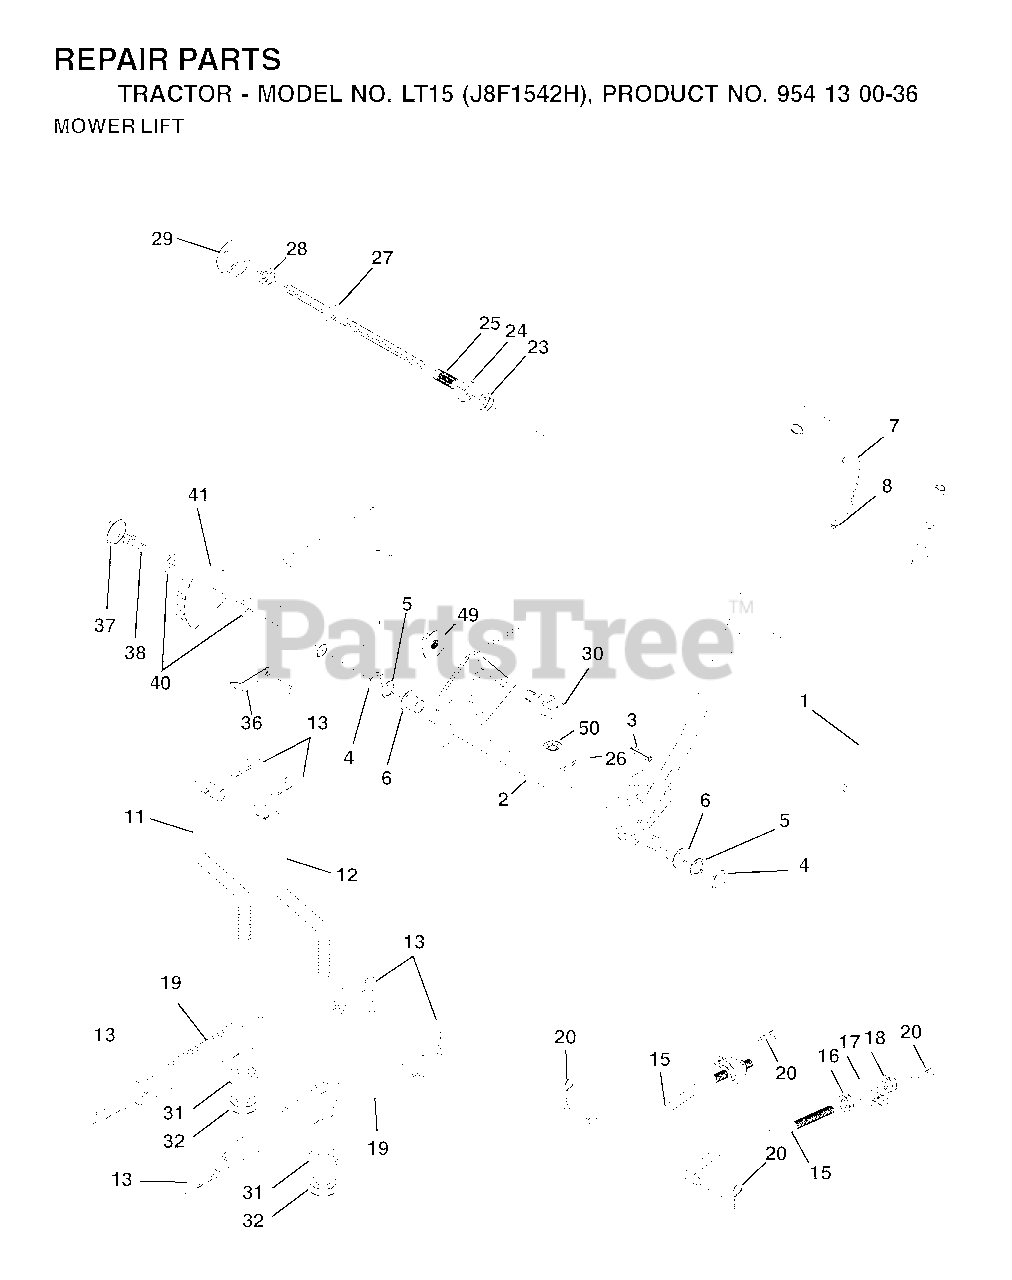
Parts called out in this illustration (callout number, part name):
1	WIRE ASM INNER W/ PLUNGER LT
2	SHAFT ASM R HANDLE
3	PIN GROOVE
4	RETAINING RING LT
6	BEARING.NYLON
7	GRIP HANDLE
11	LINK LIFT LH
12	LINK LIFT RH
13	RETAINER-SPRNG RB
15	LINK.SUSPENSION.FRONT
16	NUT
17	TRUNION
18	NUT
19	ARM.REAR.SUSPENSION
20	SPRING RETAINER
25	SPRING**
26	RETAINER CLIP
27	ROD ADJ LIFT
28	NUT
29	KNOB INF 3/8-16
31	BEARING.PIVOT.LIFT
32	NUT CROWNLOCK 3/8-24
36	POINTER, HEIGHT INDICATOR
37	PLUG,HOLE
38	SCREW 5/16-18X1
41	IND. HEIGHT STLT
49	NUT
50	NUT PUSH M
